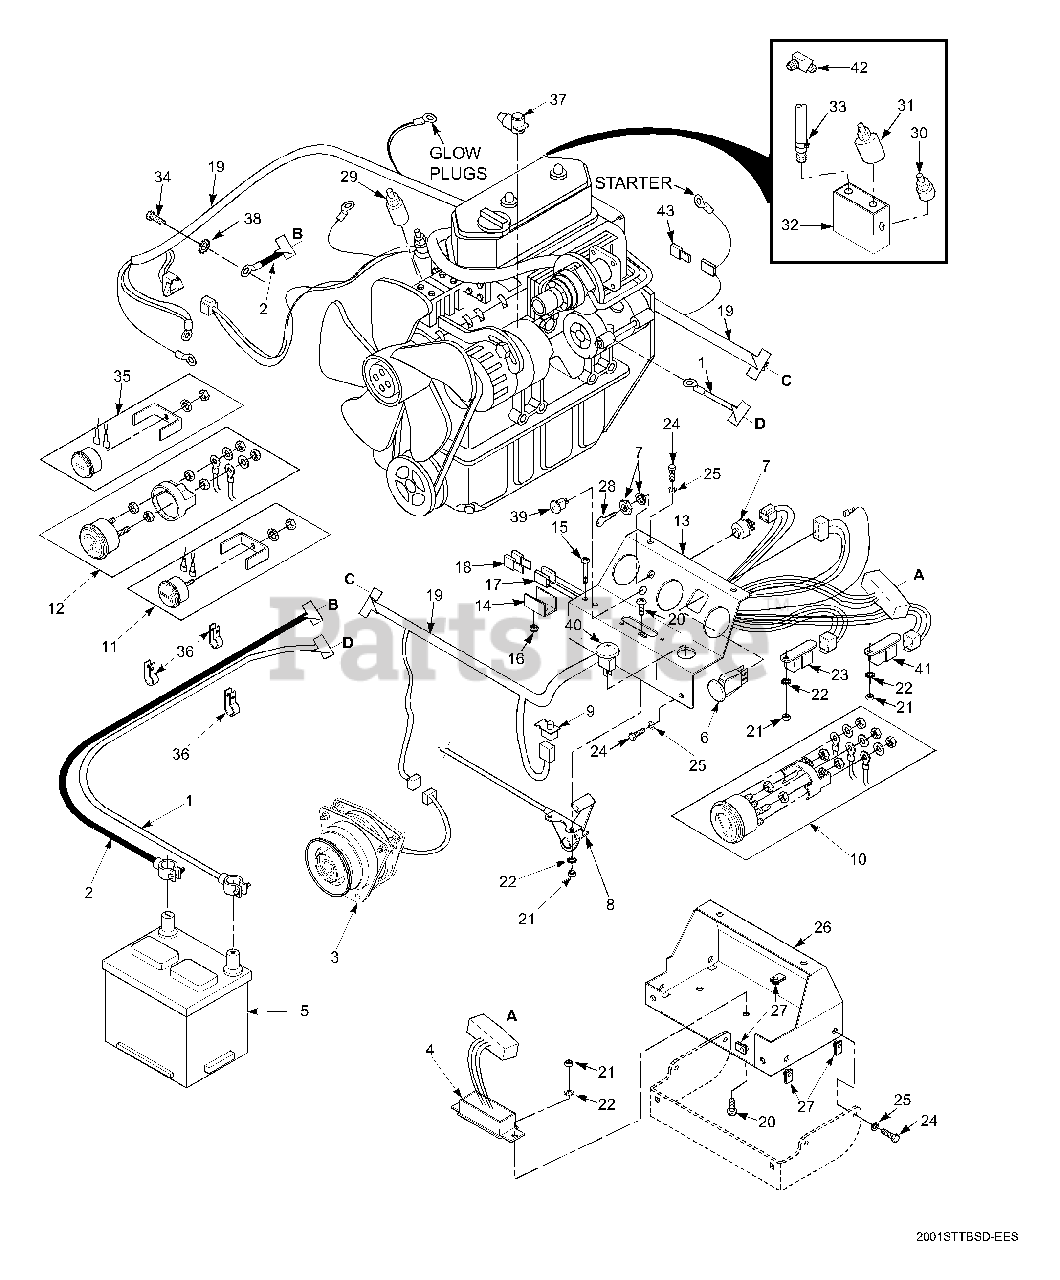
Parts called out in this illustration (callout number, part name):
1	Cable, Positive Battery
2	Cable, Negative Battery
3	Clutch, Electric PTO
4	Module, Interlock
5	Battery
6	Switch, PTO
7	Switch, Key
8	Cable, Control (Throttle, Choke)
9	Switch, Seat
10	Gauge, Water Temperature
11	Gauge, Oil Pressure
12	Gauge, Volts
13	Panel, Instrument Panel
14	Bracket, Fuse Holder
15	Screw, #10-32 x 1.5" Phillips
16	Nut, #10-32 Elastic Stop
17	Fuse Holder w/ 20 Amp Fuse
18	Fuse, 20 Amp
19	Harness, Wiring
20	Screw, #10-32 x .5" Phillips
21	Nut, Hex #10-32
22	Lock Washer #10
23	Relay
24	Bolt, Hex Head 1/4-20 x .75"
25	Lock Washer 1/4"
26	Base, Instrument Panel
27	U-Nut, 1/4-20
28	Key & Ring Assembly
29	Sender Unit, Water Temperature
30	Switch, Low Oil Pressure
31	Sender Unit, Oil Pressure
32	Manifold, Oil
33	Hose, Oil Pressure Sender
34	Bolt, Hex Head M8-1.25 x 14
35	Hour Meter
36	Clamp, Cable .5" ID
37	Boot, Positive Battery Terminal
38	Washer, Star
39	Indicator Light, Glow Plugs
40	Indicator Light, Water Separator
41	Relay, 40 Amp
42	Fitting, Oil Sender - 45 Degree
43	Fuse, 40 Amp
